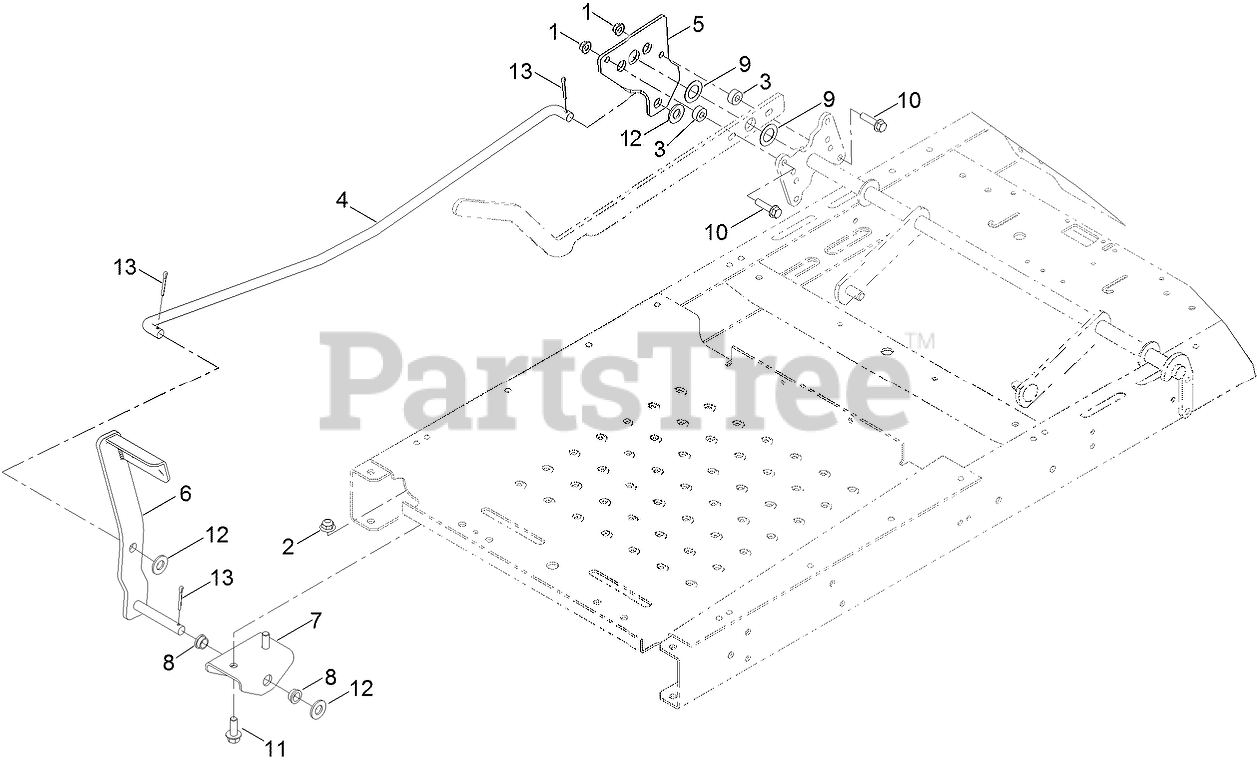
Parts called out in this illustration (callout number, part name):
1	NUT-HF
2	NUT-HF, NI
3	SPACER
4	ROD-FOOTLIFT
5	PLATE - FOOTLIFT
6	PEDAL ASM
7	BRACKET-FOOTLIFT
8	BUSHING-FLANGE
9	WASHER-THRUST
10	SCREW-HHF
11	SCREW-HHF
12	WASHER-FLAT
13	PIN-COTTER
